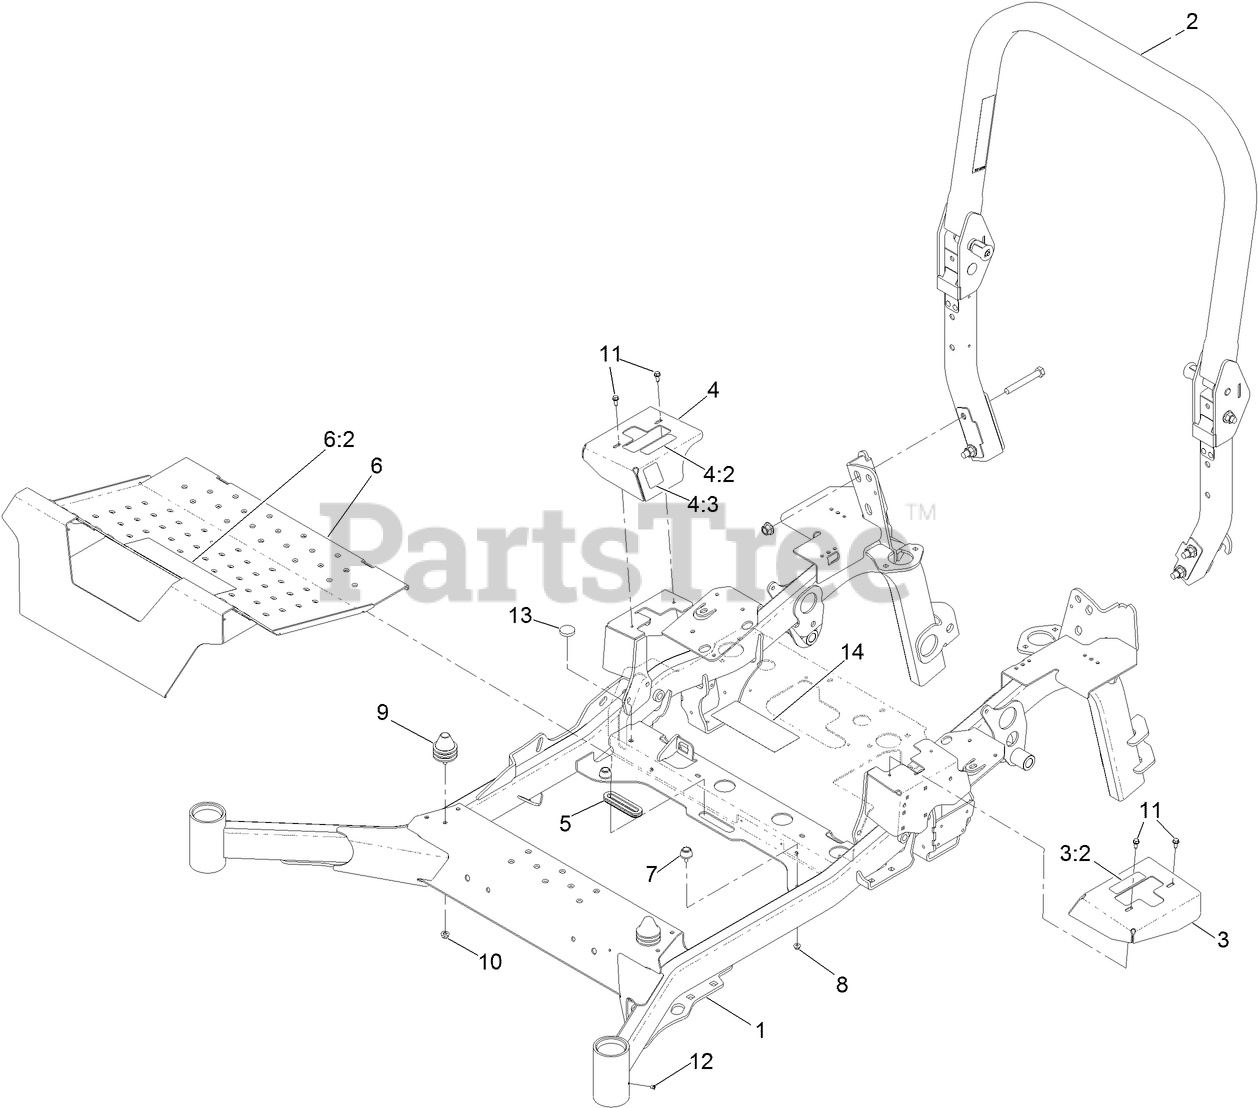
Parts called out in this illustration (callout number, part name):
1	MAINFRAME ASM, 72
2	ASM, ROPS-7500D DIESEL
3	COVER-MOTION CONTROL, LH
3:2	DECAL-CONTROL, MOTION
4	COVER-MOTION CONTROL, RH
4:2	DECAL-CONTROL, MOTION
4:3	DECAL-PARK BRAKE, CE
5	GROMMET-RUBBER
6	PAN-FLOOR
6:2	DECAL-DANGER
7	BUMPER-RUBBER
8	NUT-HF
9	ISOLATOR
10	NUT-HF, NI
11	SCREW-HWH
13	BUMPER-PUSH-IN, RUBBER
14	DECAL-SERVICE AID
